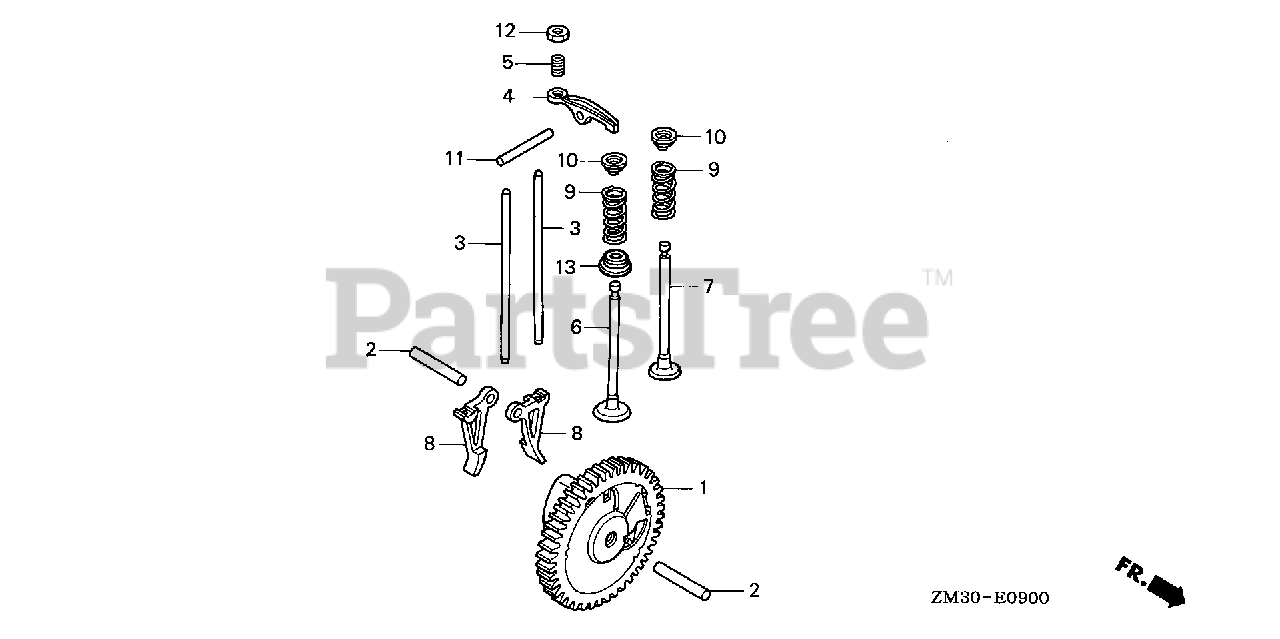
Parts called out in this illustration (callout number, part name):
1	CAMSHAFT ASSY.
2	ROLLER (5X23.8)
4	ARM, VALVE ROCKER
5	PIVOT, ROCKER ARM
6	VALVE, IN.
7	VALVE, EX.
8	LIFTER, VALVE
9	SPRING, VALVE
10	RETAINER, VALVE SPRING
11	ROLLER (4X28)
12	NUT, TAPPET ADJUSTING
